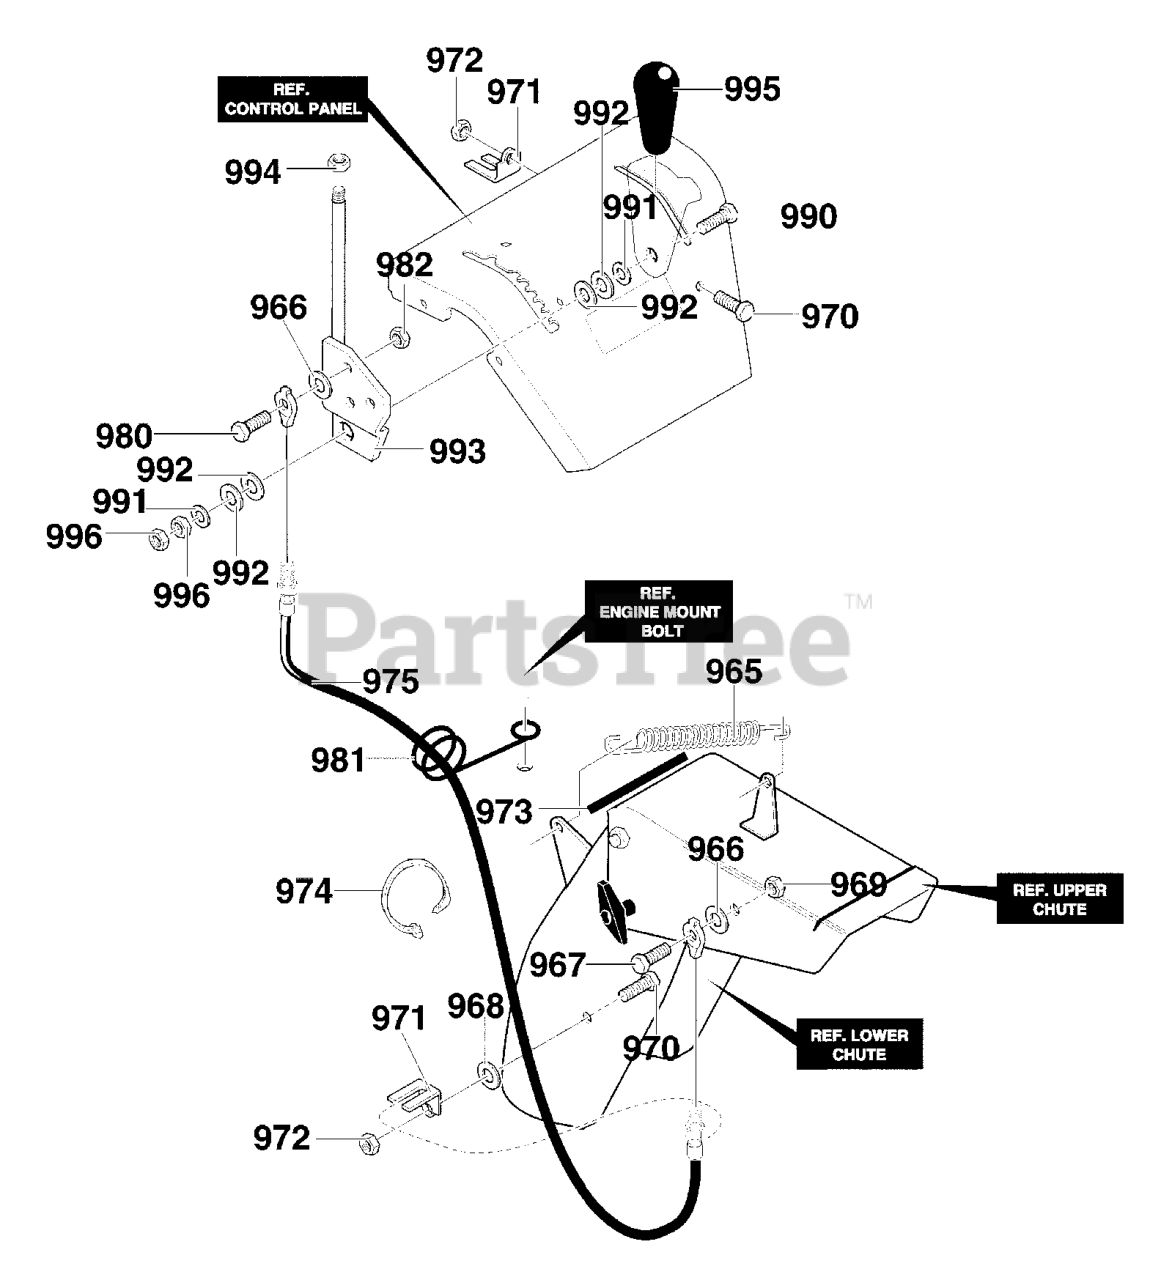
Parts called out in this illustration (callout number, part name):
965	SPRING, TENSION
966	FLATWASHER
967	BOLT, 1/4-20 HHSH
968	FLATWASHER
969	NUT, 1/4-20
970	SCREW, 5/16-18 x 0.75
971	BRACKET, CABLE CHUTE
972	NUT, 5/16-18
973	TRIM 4.50 IN.
974	CABLE TIE
975	CABLE, CHUTE CONTROL RH
980	BOLT, 1/4-20 HHSH
981	WIRE FORM REMOTE CHUTE
982	NUT, 1/4-20
990	SCREW 3/8-16X1.75
991	FLATWASHER
992	WASHER, SPRING
993	HANDLE ASSY., SPEED CONTROL
994	NUT, 3/8-16
995	HANDLE 3/8-16
996	NUT, 3/8-16
